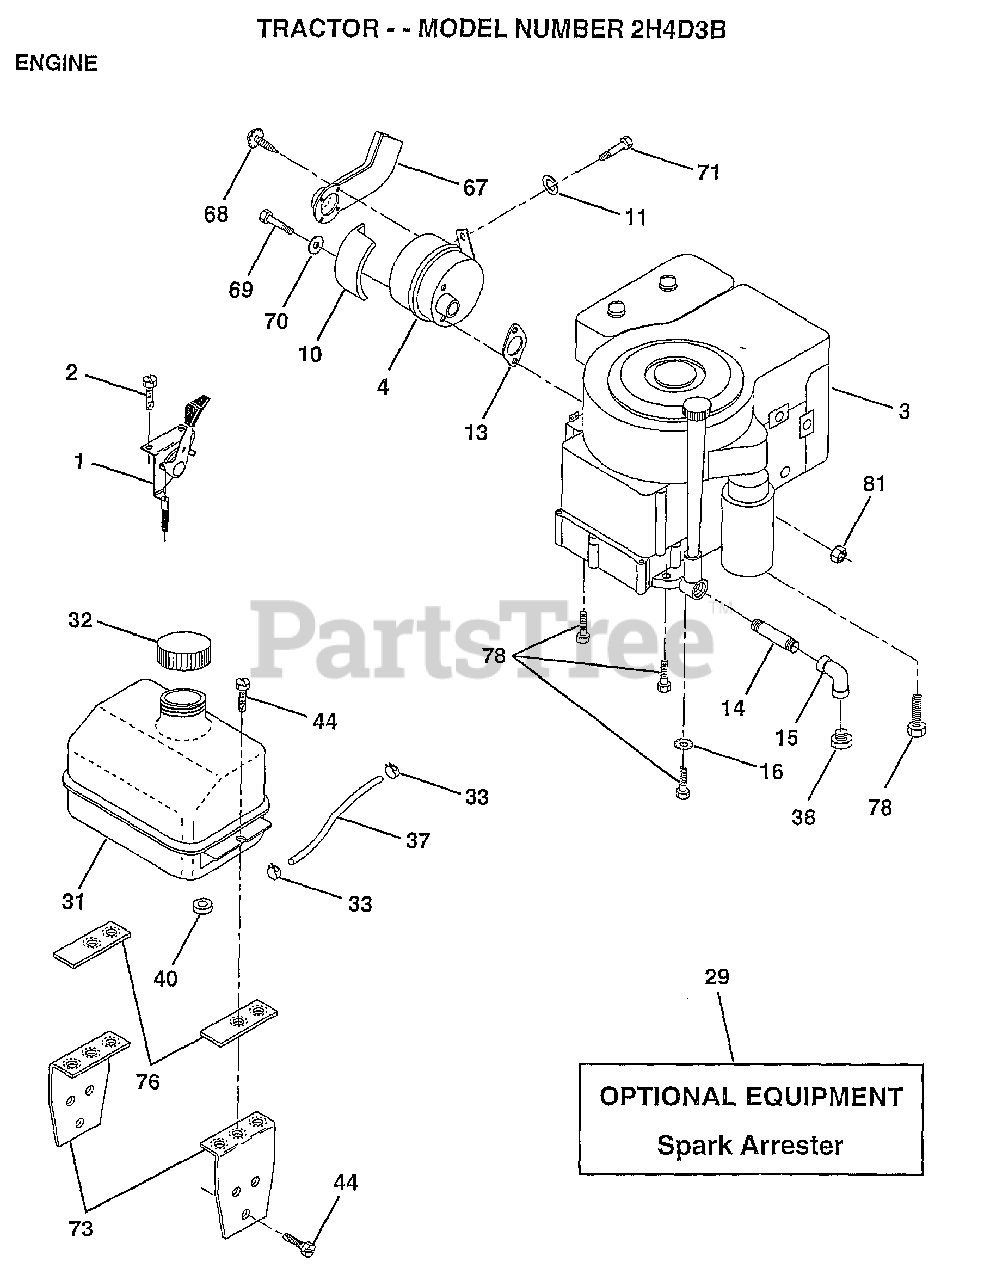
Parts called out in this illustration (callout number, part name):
1	THROTTLE CONTROL
2	SCREW LT
4	MUFFLER LTV
10	SHIELD HEAT LTV
11	LOCKWASHER
13	GASKET ENG 1 313 LD TIN PLATED
14	PIPE NIPPLE
15	ELBOW
16	LOCKWASHER
31	TANK.FUEL.LT.
32	CAP ASM FUEL
33	HOSE CLAMP
37	LINE FUEL
44	SCREW
67	DEFLECTOR MUFFLER
69	"BOLT,HEX"
70	WASHER T
71	BOLT HXHD FIN
73	"CLAMP,FUEL TANK T"
76	BRKT FUEL TANK T
78	SCREW
81	NUT
